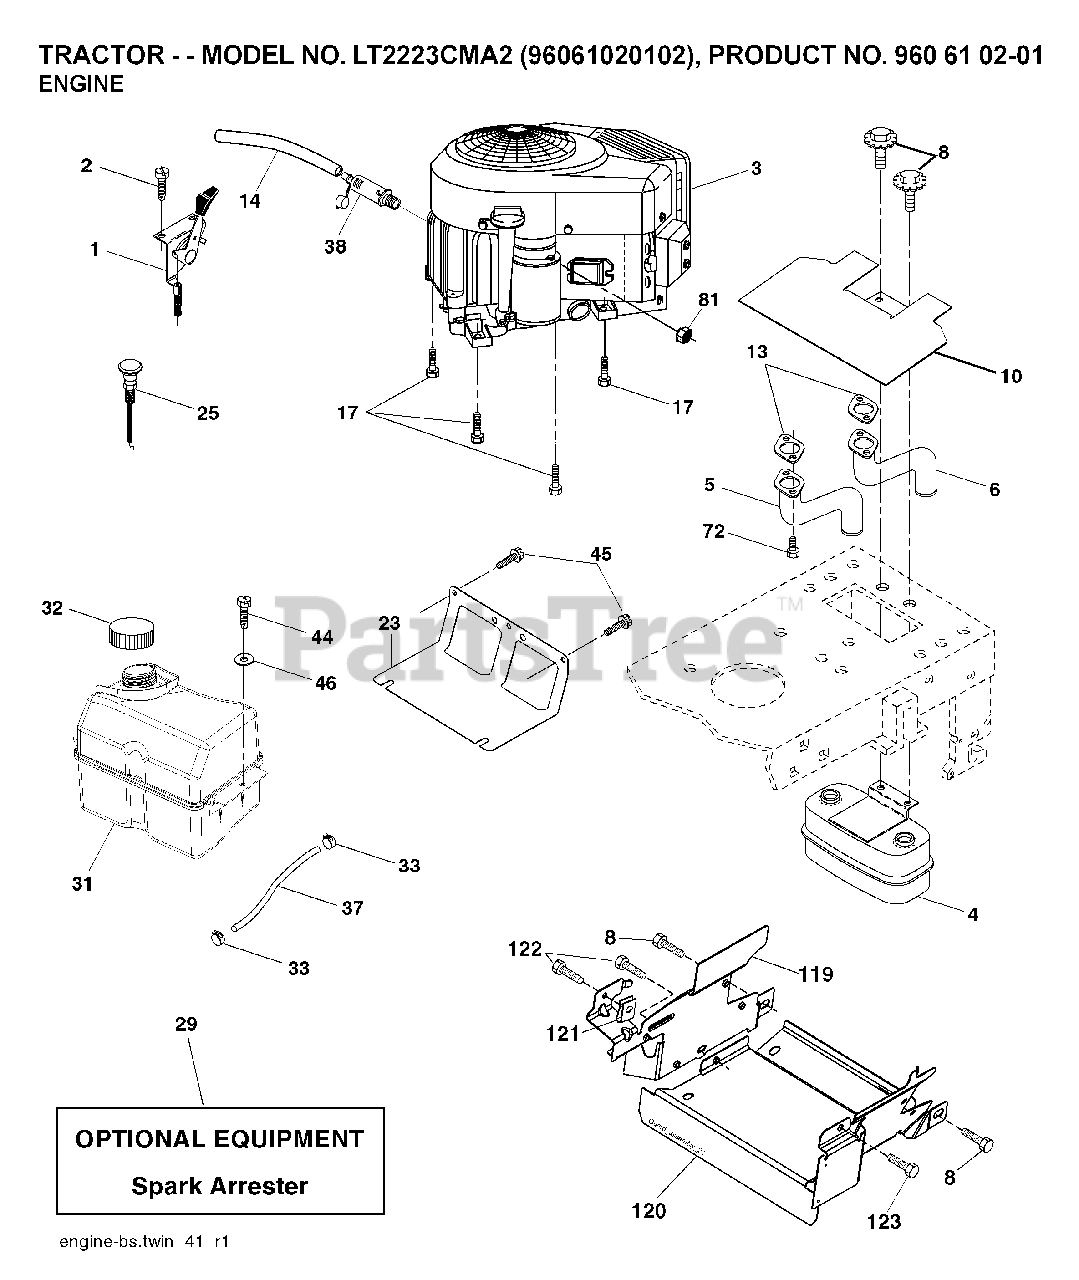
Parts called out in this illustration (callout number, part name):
1	THROTTLE CABLE
2	SCREW
4	MUFFLER.TWIN.CYL.LOW.TONE
5	EXHAUST TUBE RH
6	TUBE MANIFOLD LH
8	BOLT, 5/16-18 X 1 3/4
10	RP SHIELD HEAT MUFFLER
13	GASKET.MUFFLER
14	TUBE, DRAIN OIL ASM.
17	SCREW.3/8-16
23	SHEILD.BROWNING.DBR.GUARD
25	CONTROL CHOKE
29	ARRESTER SPARK (OPTIONAL)
31	FUEL TANK FRT 2 GAL.
32	FUEL CAP
33	HOSE CLAMP
37	LINE.FUEL.20
38	PLUG DRAIN OIL EASY
44	SCREW HEXWSHR 1/4-20X3/4
45	SCREW, 3/8-16X3/4
72	SCREW.SOCKET.HEAD.5/16-18
81	NUT
122	SCREW.1/4-20X5/8
123	SCREW, 5/16-18 X 1/2
